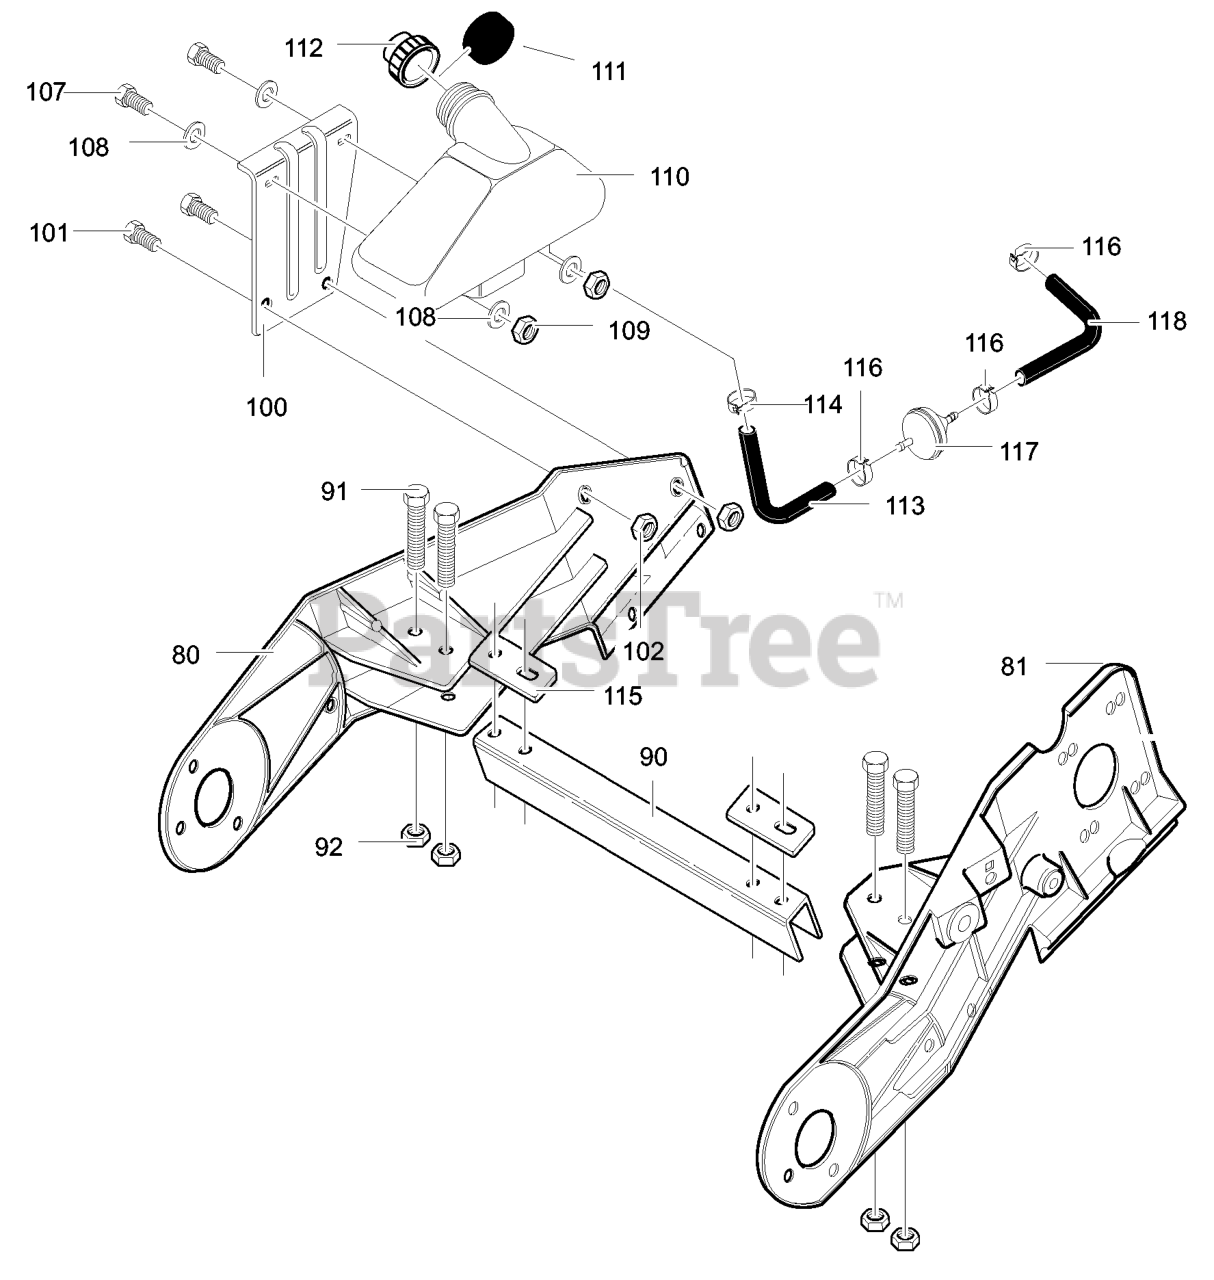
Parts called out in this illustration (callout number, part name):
80	FRAME, RIGHT SIDE
81	FRAME, LEFT SIDE
90	CHANNEL, FRAME
91	SCREW, 1/4-20X2.00
92	NUT, 1/4-20
100	BRKT, FUEL TANK
101	SCREW, 1/4-20X .75
102	NUT, 1/4-20
107	SCREW, 1/4-20X .75
108	WASHER, FLAT
109	NUT, 1/4-20
110	TANK, FUEL 1.5QT
111	RING, FUEL TANK
112	CAP, FUEL
114	CLAMP, HOSE
115	PLATE, SUPPORT
116	CLAMP, HOSE
117	FILTER, IN-LINE
